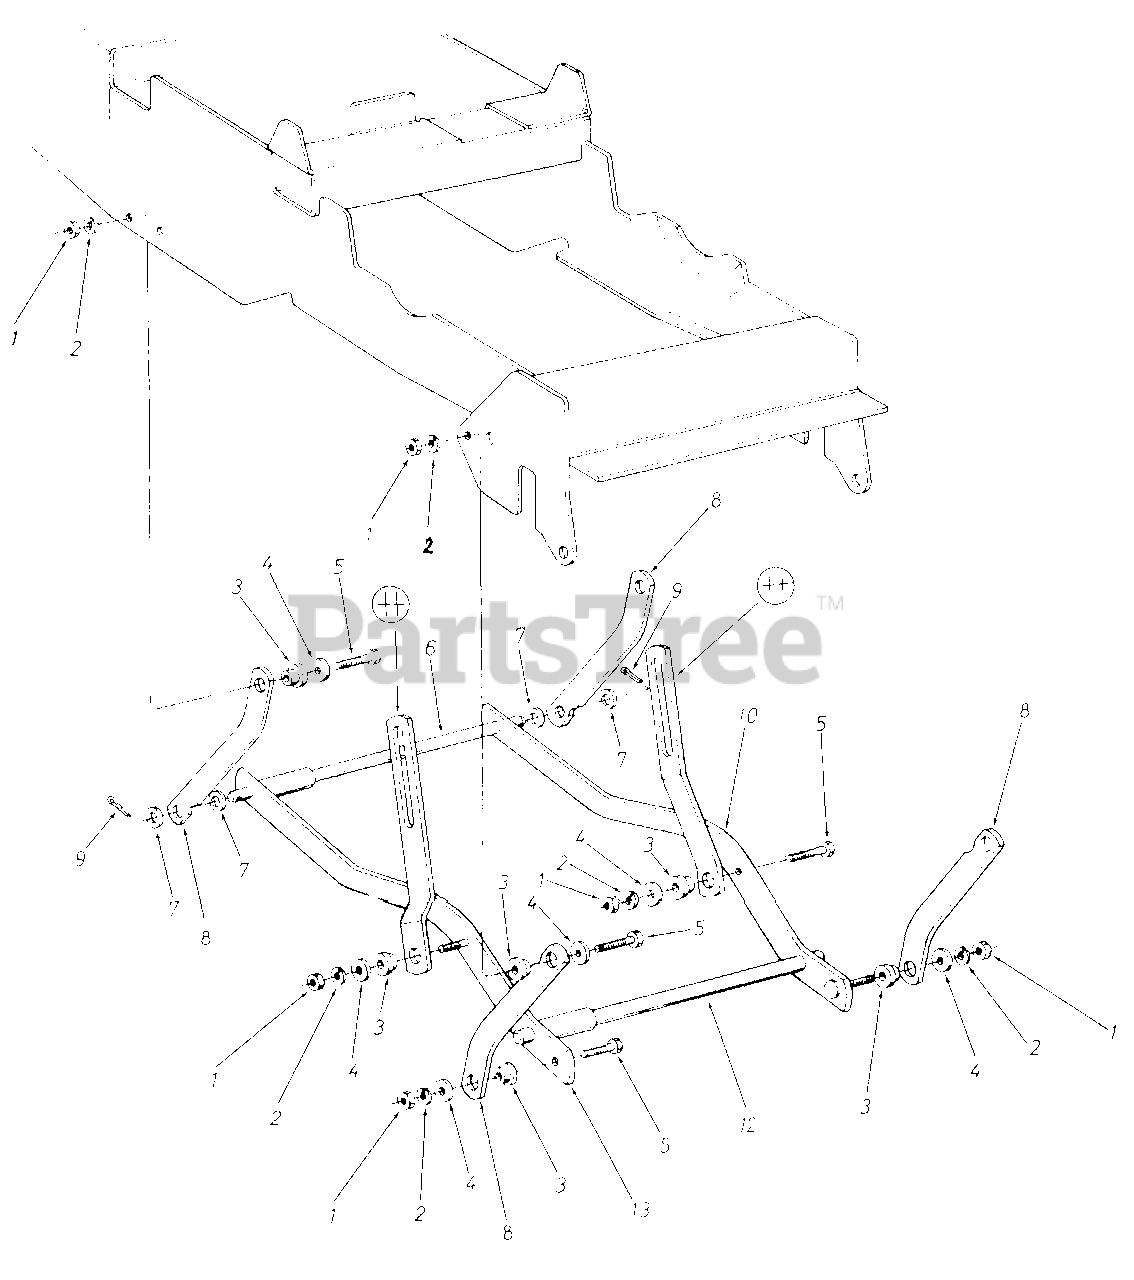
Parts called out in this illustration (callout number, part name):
1	Hex Nut 3/8 24 Thd.*
2	L Wash. 3/8" Scr. Heavy Duty*
3	Shoulder Spacer
4	Fl.-Wash. 3/8" I.D. x 1.0" O.D.
5	Hex Scr. 3/8 24 x 1.50" Lg. Grade 5
6	Cross Shaft Ass'y.-Rear
7	Fl.-Wash. 5/8" I.D. x 1-1/8" O D.
8	Lift Arm
9	Cotter Pin 5/32" Dia, x1.25"Lg.*
10	Lift Arm Link Ass'y.-LH.
12	Cross Shaft Ass'y.-Front
13	Lift Arm Link Ass'y-R.H.
